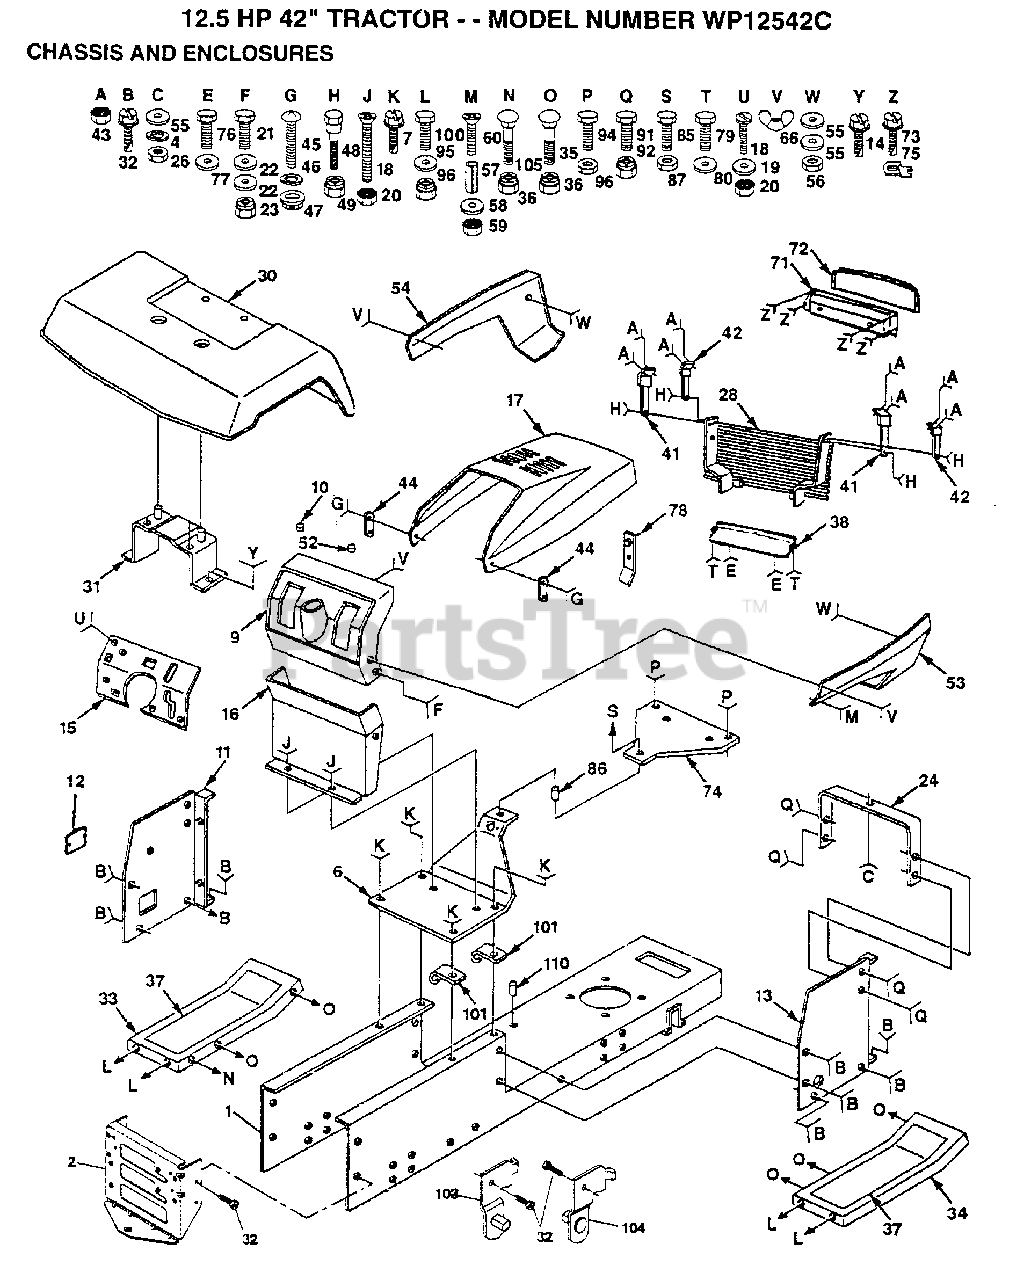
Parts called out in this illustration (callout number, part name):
4	LOCKWASHER
6	SADDLE SLKSCR 6SP
7	SCREW
9	DASHBOARD BLACK
10	PLUG BUTTON T
11	PANEL.DASH.LH
12	COVER ACCESS
13	PANEL.DASH.RH
14	SCREW
15	PLATE.DASH.SILKSC
16	DASH ASSY LT
18	SCREW
19	WASHER
21	BOLT
22	WASHER
23	NUT
24	SUPPORT ASS'Y
30	FENDER
31	BRKT FENDER
32	SCREW
35	BOLT
36	NUT
37	FOOTREST PAD
43	NUT
44	HOOD LATCH T
45	SCREW
46	LOCKWASHER
47	WELDNUT
52	PLUG-DASH T
54	"PANEL,SIDE LH"
55	WASHER PM
57	SPACER LT
58	WASHER
60	SCREW
72	LENS LT
74	PLATE.SUPT.BATTER
75	"""J"" FASTENER LT"
76	SCREW
77	WASHER
79	SCREW HEX CRT
80	WASHER
85	BOLT
86	SPACER
87	NUT
91	BOLT
94	BOLT
95	WASHER
96	NUT
100	BOLT
101	CLIP T
103	BRACKET ASM LH
104	BRACKET ASM RH
